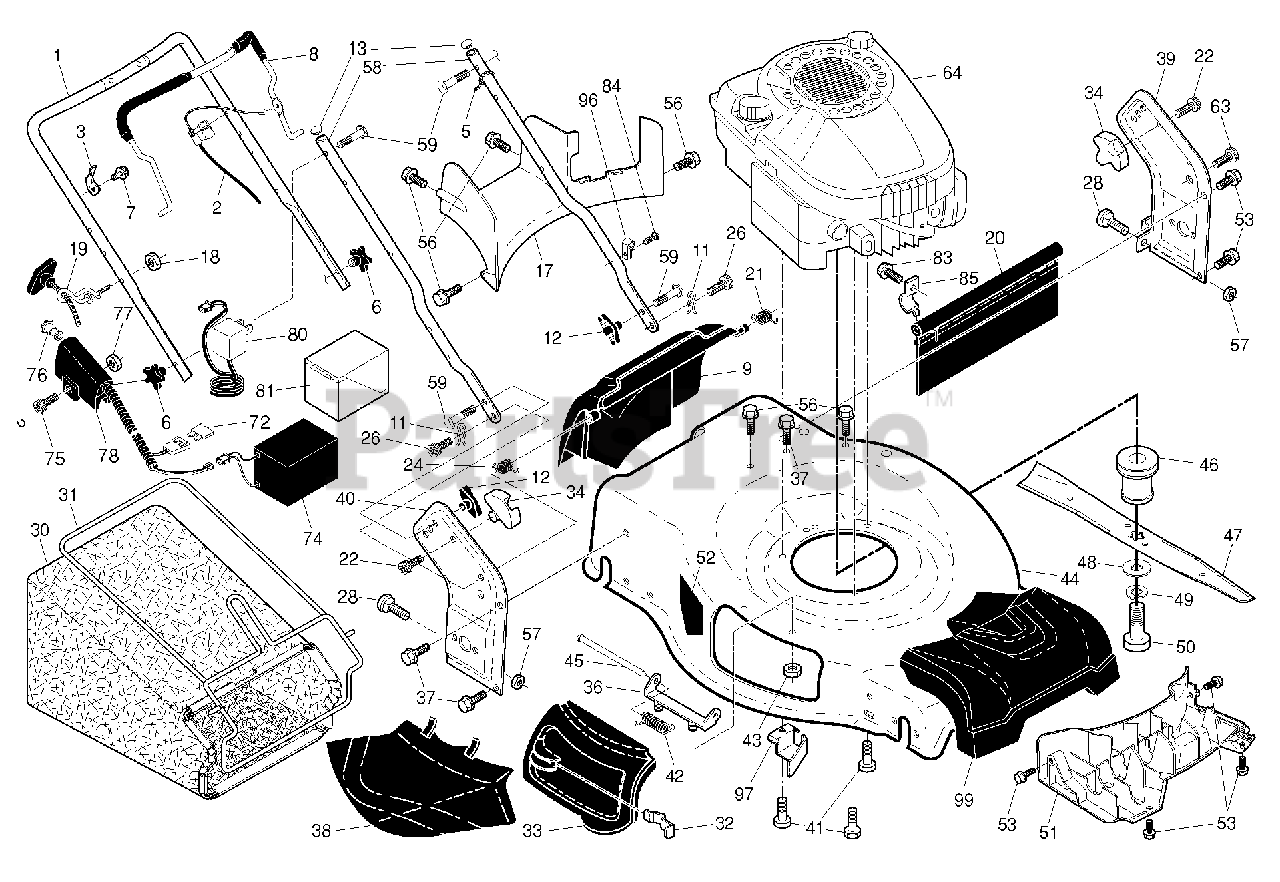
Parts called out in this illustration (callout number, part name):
1	HANDLE.UPPER.3.POS.BS.AW2.GREY
2	CABLE.MZR.50.SNAP-IN
3	BRACKET.UPSTOP.RT
5	TIE GUIDE
6	KNOB.HANDLE.PLASTIC.STAR.BLACK
8	BAIL.OVER.MOLD.ERGO.MZR.ORANGE
9	DOOR.REAR.ASM.22+.HUSQ.FG/RGD
11	COTTER.HAIRPIN.DOOR/HANDLE.PIV
12	KNOB, DEFLECTOR
13	PLUG.PLASTIC.7/8".14-20.GAUGE
17	BAFFLE.REAR.22+RGD.AWD.PLASTIC
18	NUT
19	RB GUIDE.ROPE.STD.BLK.ZIN WSL
20	SKIRT.REAR.22PLUS.RGD.LW(2 2MC
21	SPRING.LH.BLACK
22	SCREW.PAN.HEAD.#10
24	SPRING.RH.GRAY
26	SCREW,DOOR/HANDLE.PIVOT
28	BOLT
30	GBAG.B5610247T.SIL.HUSQ.BLUE
31	RB FRAME.GBAG.22PLUS
32	LATCH.DOOR.ZINC
33	DOOR.MULCH.22 PLUS.HUSQ.GREY
34	BRACKET.GRASSBAG.ATTACHING.BLK
36	BRACKET.ASM.HINGE.21.FWGD.
37	BOLT.5/16HEX.WHS.HD
38	DEFLECTOR.CLIPPING.22.BLACK
39	BRACKET.ASM.HNDL.LT.22+.GREY
40	BRACKET.ASM.HNDL.RT.22+.GREY
41	BOLT 3/8-16X1-1/8
42	SPRING.TORSION
43	NUT.HEX.FLANGE.1/4
44	HOUSING.22+.RWD.HUSQ.ORANGE
45	ROD.HINGE.21
46	ADAPTER.BLADE.25MM.3MPH
47	BLADE.22+4N1.2PIN.5STAR.(P07)
48	WASHER,HARDEN
49	LOCKWASHER
50	SCREW, HEX HD 3/8-24 X 1-3/8
51	BAFFLE.FRONT.22+PLASTIC.(2 2)
52	DANGER DECAL
53	SCREW.HI-LO.5/16 X.75
56	SCREW.HX.13X.750
57	NUT.FLANGE.5/16
58	HANDLE.LOWER.22+BT.2PC.GRY
59	BOLT, HANDLE 5/16-18X1.75
74	BATTERY.12V.22+RWGD
75	BOLT.M6-1X40.T30
76	BUTTON.KEY.CYLINDER.BLACK
77	Lock Nut, M6-1 Nyloc Insert
78	CNTRL.SUBASM.22+RGD.PUSH.BUTTO
80	RP CHARGER.12V.0.1A
81	BOX.BATTERY.22+RGD.GREY
83	TAPPING SCREW
84	FASTENER.PUSH.O.250X0.783
85	BRACKET.SKIRT.22+.BZP
96	CLIP.CABLE.BLK
97	BRACKET.BELT.GUIDE.22+.BZP
99	COVER.ASM.FRONT.SHROUD.HUSQ.
